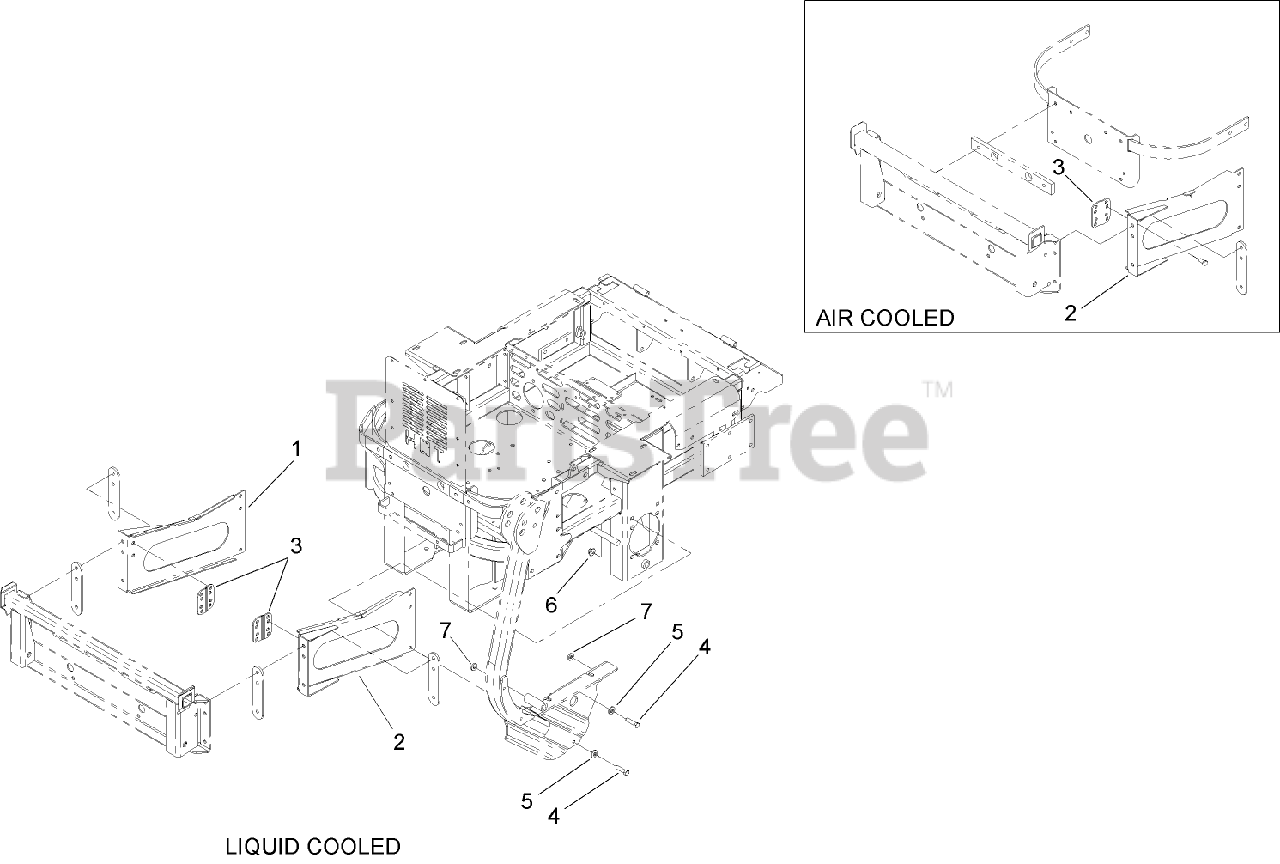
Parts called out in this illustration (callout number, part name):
1	LH FRAME BRACKET ASM
3	BRACKET-STIFFENER
4	SCREW-HH
5	WASHER-BELLEVILLE
6	NUT-HF
7	SPACER
